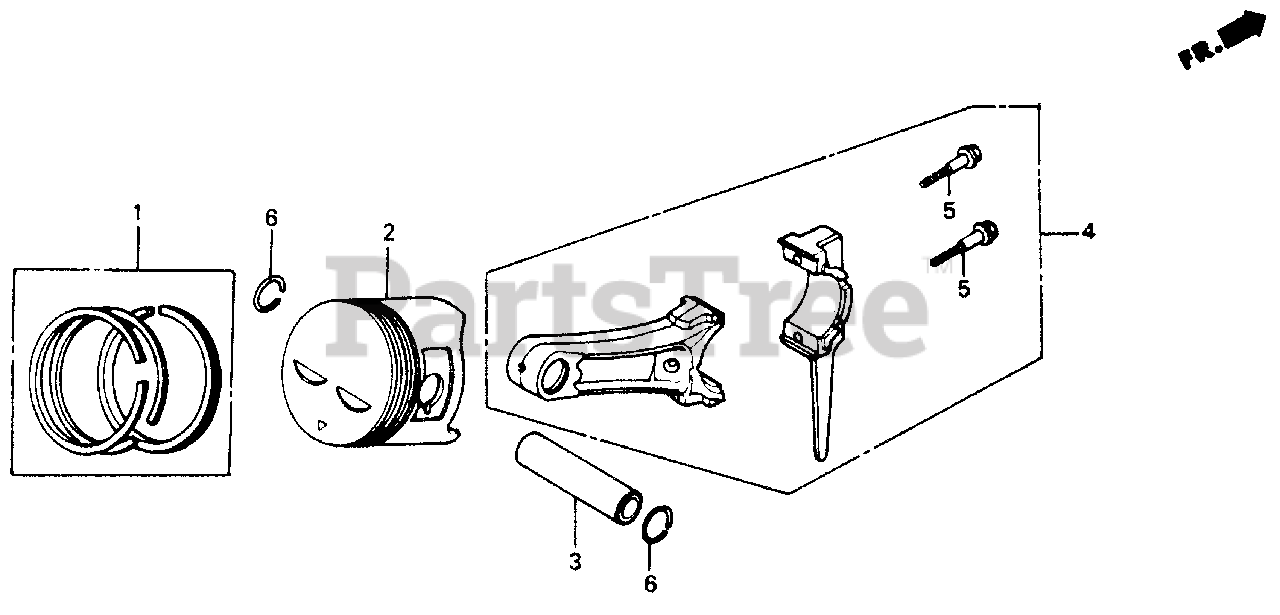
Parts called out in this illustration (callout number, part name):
1	RING SET, PISTON (STD) (NIPPON)
1	RING SET, PISTON (STD) (TEIKOKU)
1	RING SET, PISTON (0.25)
1	RING SET, PISTON (0.50)
1	RING SET, PISTON (0.75)
2	PISTON (STD)
2	PISTON (0.25)
2	PISTON (0.50)
2	PISTON (0.75)
3	PIN, PISTON
4	ROD ASSY., CONNECTING (STD)
4	ROD ASSY., CONNECTING (0.25 LOWER SIZE)
5	BOLT, CONNECTING ROD
6	CLIP, PISTON PIN (18MM)
